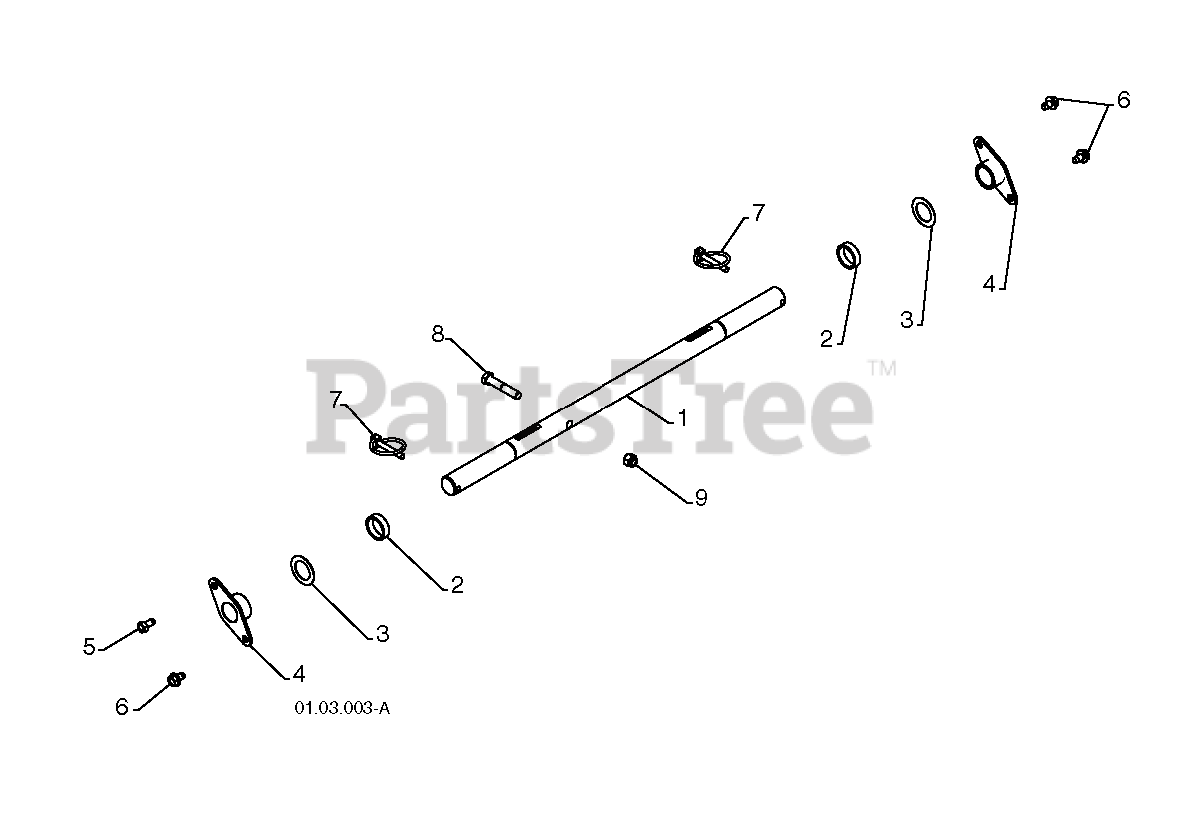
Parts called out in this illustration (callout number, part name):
1	SHAFT.AXLE.POWER.STEERING.HYD
2	SPACER.AXLE.RH
3	WASHER 1.00
4	BEARING, AXLE
6	Screw 5/16-18 x 1/2 Hex, Self Tapping 5/16-18 x 1/2
7	PIN KLIK, 1/4
8	CAP.SCREW.HEX.HD.3/8-16
9	NUT
